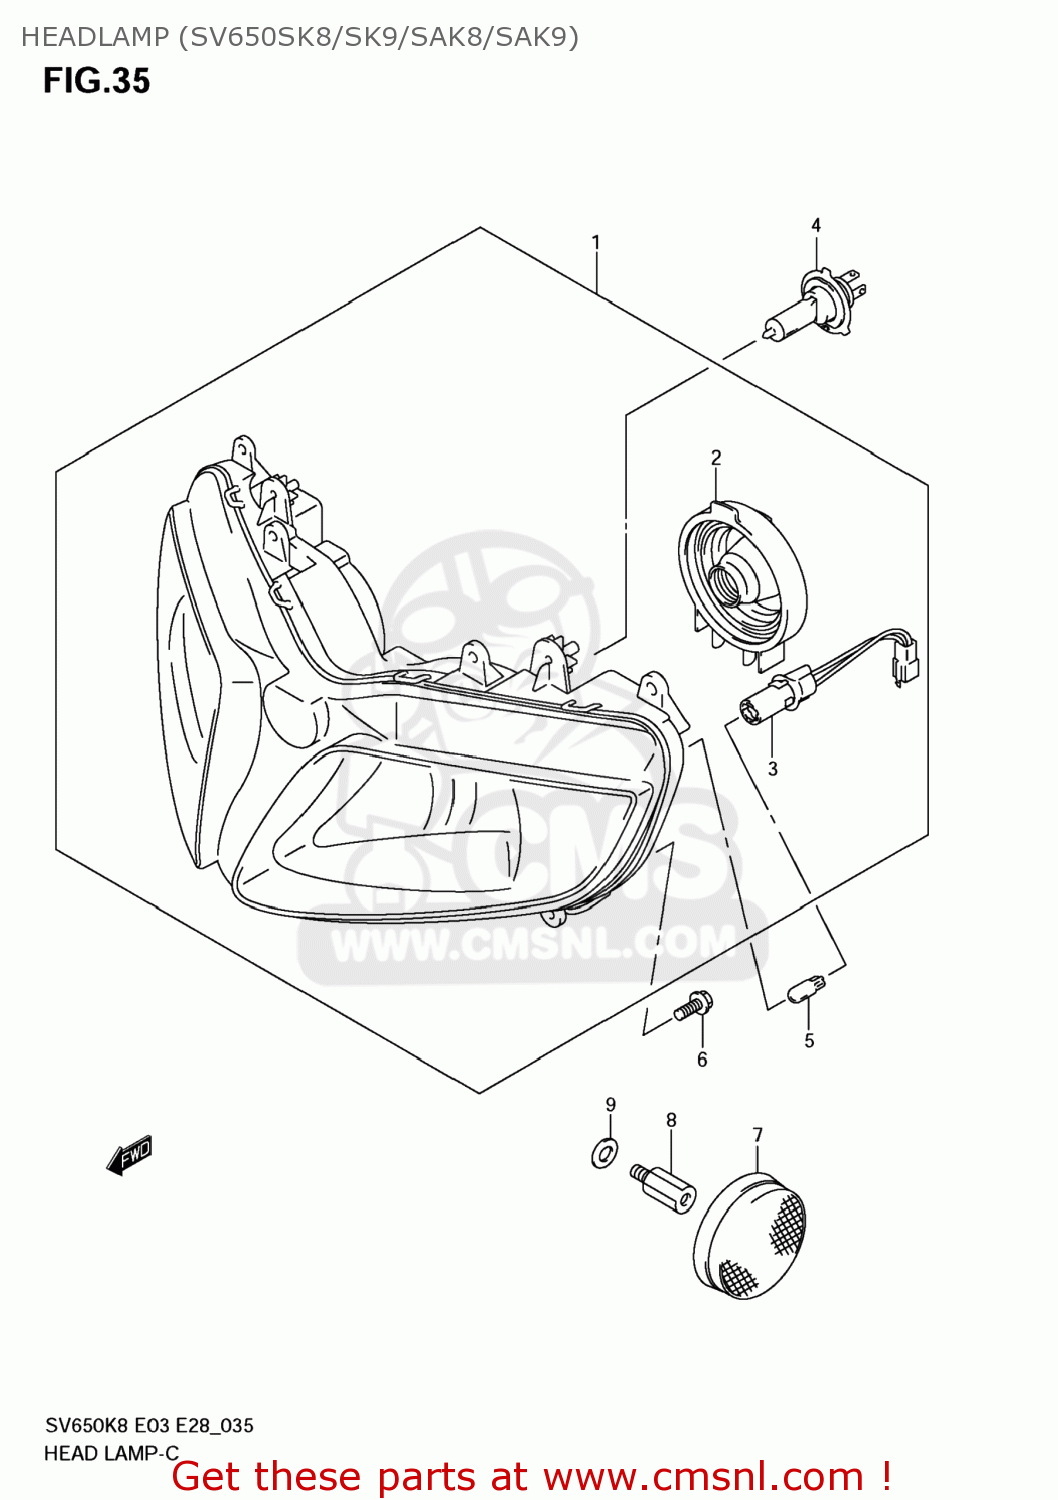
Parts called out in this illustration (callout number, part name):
1	HEADLAMP ASSY
2	COVER,SOCKET
3	CORD ASSY
4	BULB(12V60/55W,H4)
5	BULB(12V5W)
6	SCREW
7	REFLECTOR,REFLEX
8	BOLT(5X10)
9	WASHER
